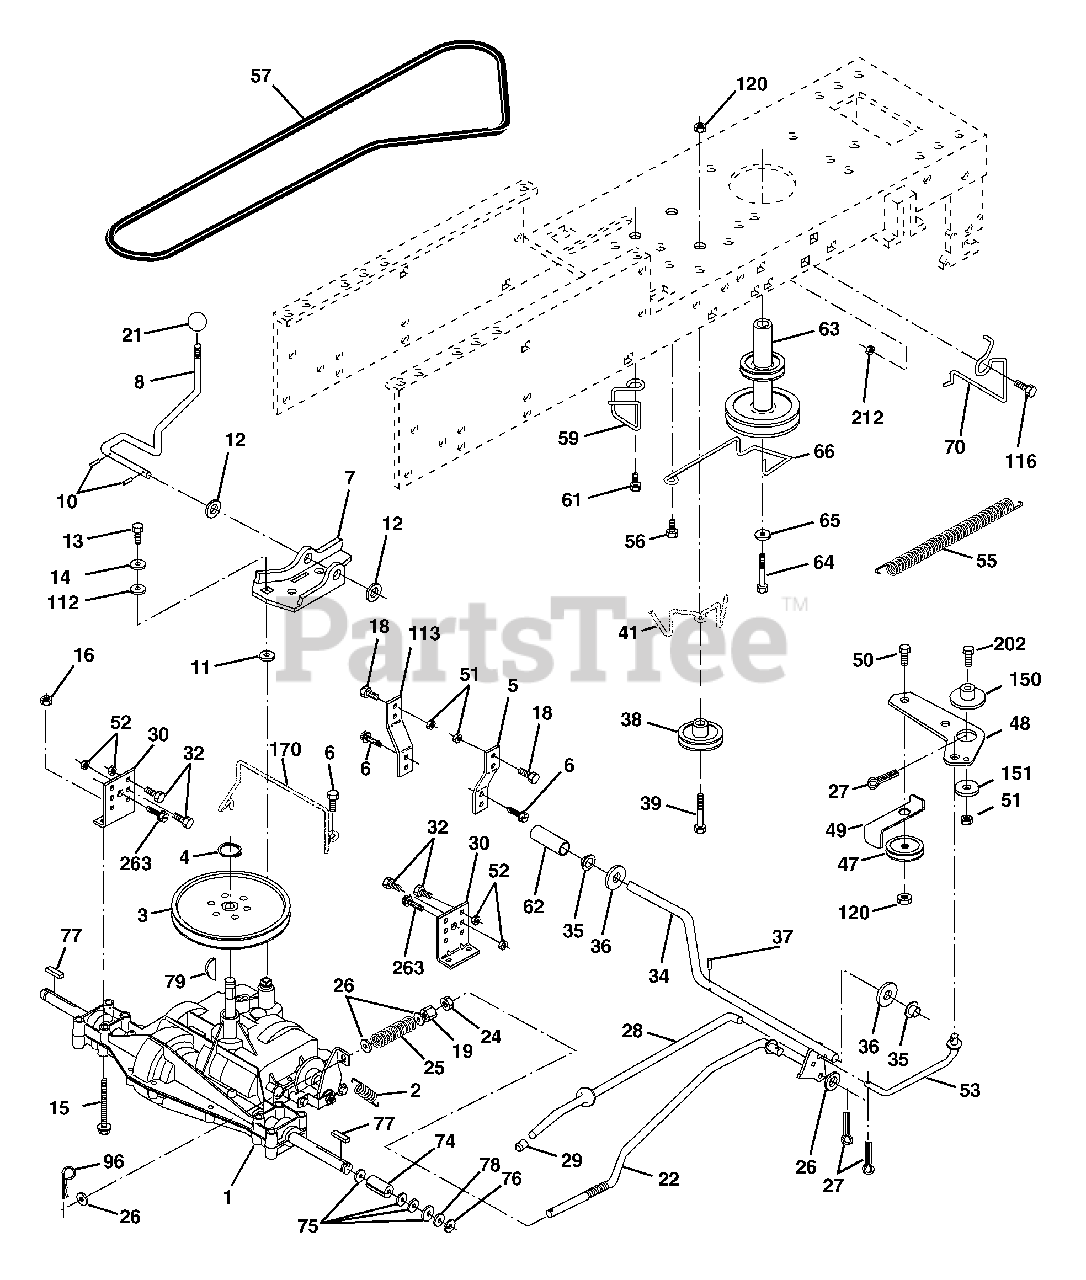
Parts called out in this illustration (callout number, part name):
2	Spring Return Brake T/a Zinc
3	Pulley Transaxle 18/20" tires
4	Ring Retainer # 5100-62
5	Strap Torque 30 Degrees
6	Screw 5/16-18 x 3/4
7	Bracket Saddle Shift T/a
8	Rod Shf Sdl LY/YT Str Blk
10	Pin Cotter 1/8 x 1 Cad
11	Washer Plate 388 Sq Hole
12	Washer 15/32 x 3/4 x 16 Ga.
13	Bolt 1/4-28 unf Gr. 8 W/Patch
14	Washer Lock Hvy Helical 1/4
15	Bolt Hex Flghd 5/16-18 x Gr. 5
16	Nut 5/16-18
18	Bolt Fin Hex 3/8-16 unc x 1 Gr. 5
19	Nut Lock Hex W/Ins. 3/8-16 unc
21	Knob Rd 1/2-13 Plstc Thds
22	Rod Brake Blk Zinc 26 840
24	Nut Hex Jam 3/8-16 unc
25	Spring Rod Brake 2 00 Zinc
26	Washer 13/32 x 13/16 x 16 Ga.
27	Pin Cotter 1/8 x 3/4 Cad
28	Rod Brake Parking Lt/Yt
29	Cap Brake Parking
30	Bracket Mtg Transaxle
32	Bolt Hex Hd 5/16-18 unc x 3/4
34	Shaft Asm Pedal Foot Nibbed
35	Bearing Nylon Blk 629 Id
36	Washer 21/32 x 1 x 16 Ga.
37	Pin Roll 3/16 x 1"
38	Pulley Composite Flat
39	Bolt Rdhd 3/8-16 unc x 2-3/4 Gr. 5
41	Keeper Belt Idler
47	Pulley Idler V Groove Plastic
48	Bellcrank Asm. Clutch
49	Retainer Belt Style Spring
50	Bolt 3/8-16 x 1-1/2 Gr. 5
51	Nut Crownlock 3/8-16 unc
52	Nut Crown Lock 5/16-18
53	Link Clutch 7 66
55	Spring Return Clutch 6 75
56	Screw 3/8-16 x 1-1/4
57	V-Belt Gd Drive 9530
59	Keeper Belt Centerspan
61	Screw 3/8-16 x .875
62	Cover Pedal Blk Round
63	Pulley Eng Cl Cable
64	Bolt Hex 7/16-20 x 4 Gr. 5-1.5 Thr.
65	Washer Lock Hlcl Spr 7/16
66	Keeper Belt Engine FP
70	Guide Belt Mower Drive RH
74	Spacer Axle
75	Washer 25/32 x 1-1/4 x16 Ga.
76	E-ring #5133-75
77	Key Square 2 0 x 1845/ 1865
78	Washer 25/32 x1-5/8 x 16 Ga.
79	Key Woodruff #9 3/16 x 3/4
96	Retainer Spring 1
112	Washer 9/32 x 3/4 x 10 Ga.
113	Strap Torque LH LT
116	Bolt 3/8-16 x 1
120	Nut Lock Flg 3/8-16
150	Spacer Retainer
151	Washer 13/32 x 2 x 10 Ga.
170	Keeper Belt Transaxle Gear
202	Bolt Carr. Sh 3/8-16 x 1-3/4 Gr. 5
212	Nut Hex Flange Lock
263	Screw Hexwsh Thdr. 3/8-16 x 3/4
